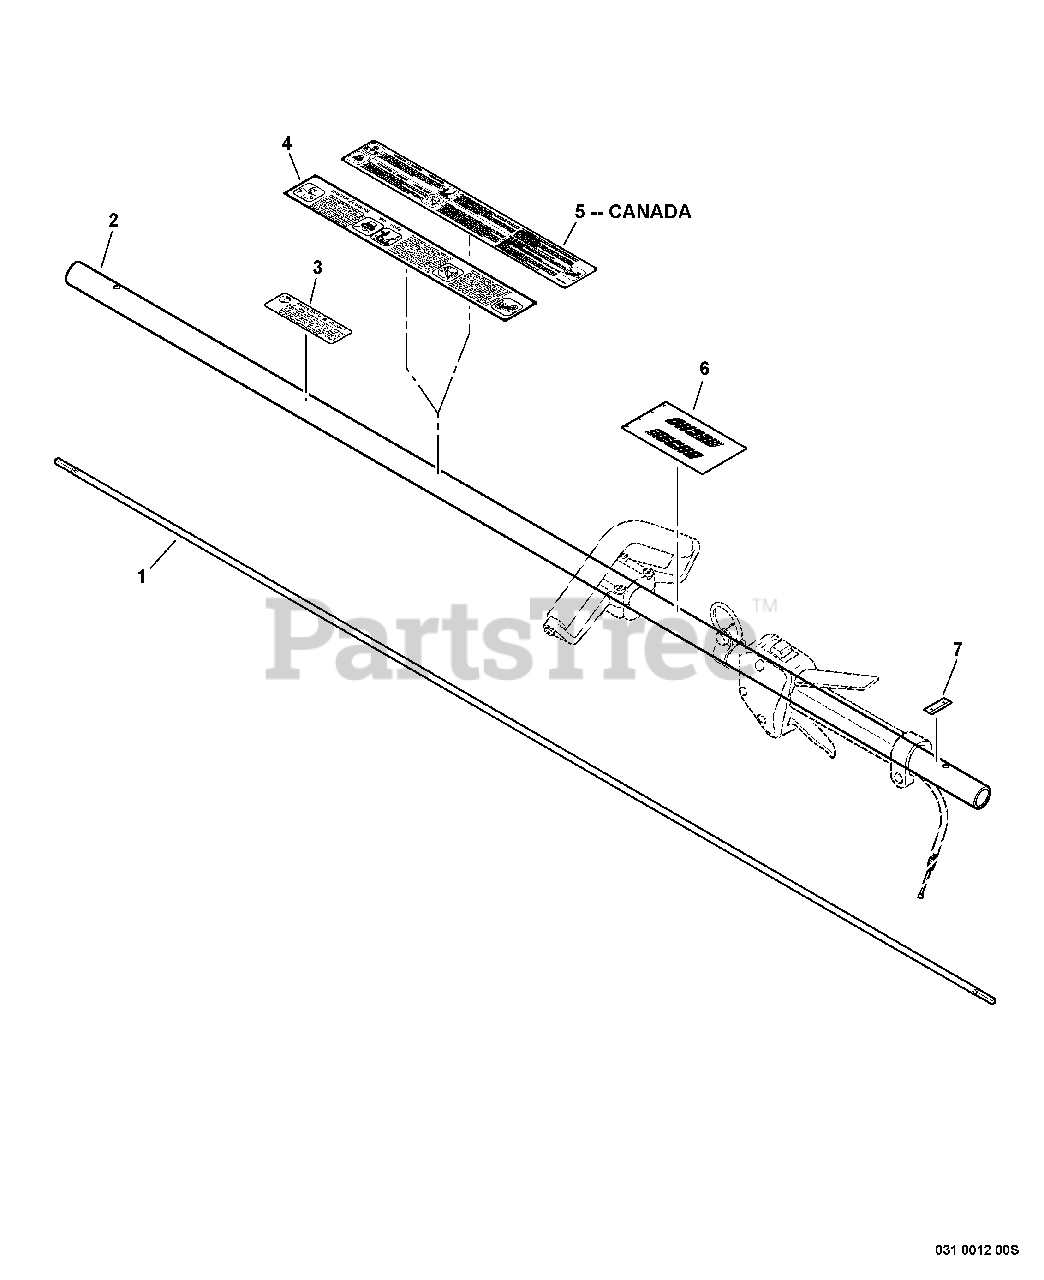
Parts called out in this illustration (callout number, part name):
1	DRIVESHAFT - SOLID
2	MAIN PIPE ASSY
3	LABEL - CAUTION -- SPANISH
4	LABEL - CAUTION
5	LABEL - CAUTION
6	LABEL - HANDLE LOCATION
7	LABEL - ALIGNMENT
